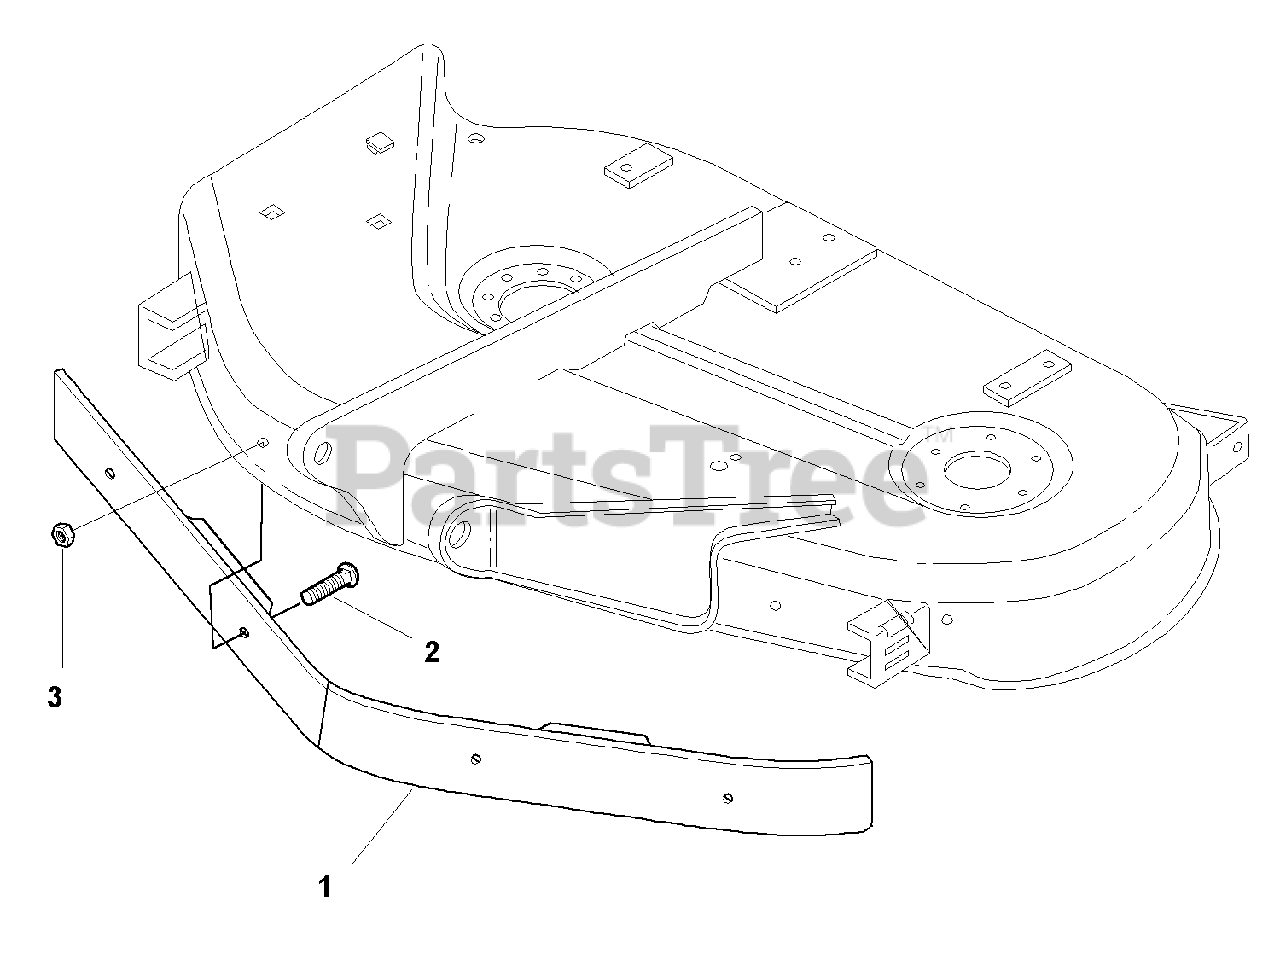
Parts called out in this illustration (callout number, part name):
1	BAFFLE, Blowout for 38" Mower
2	CARRIAGE BOLT, 5/16-18 x 3/4
3	NUT, Hex Flange Lock, 5/16-18
4	Anti-Blowout Baffle Kit, (Includes Ref. Nos. 2 & 3)
